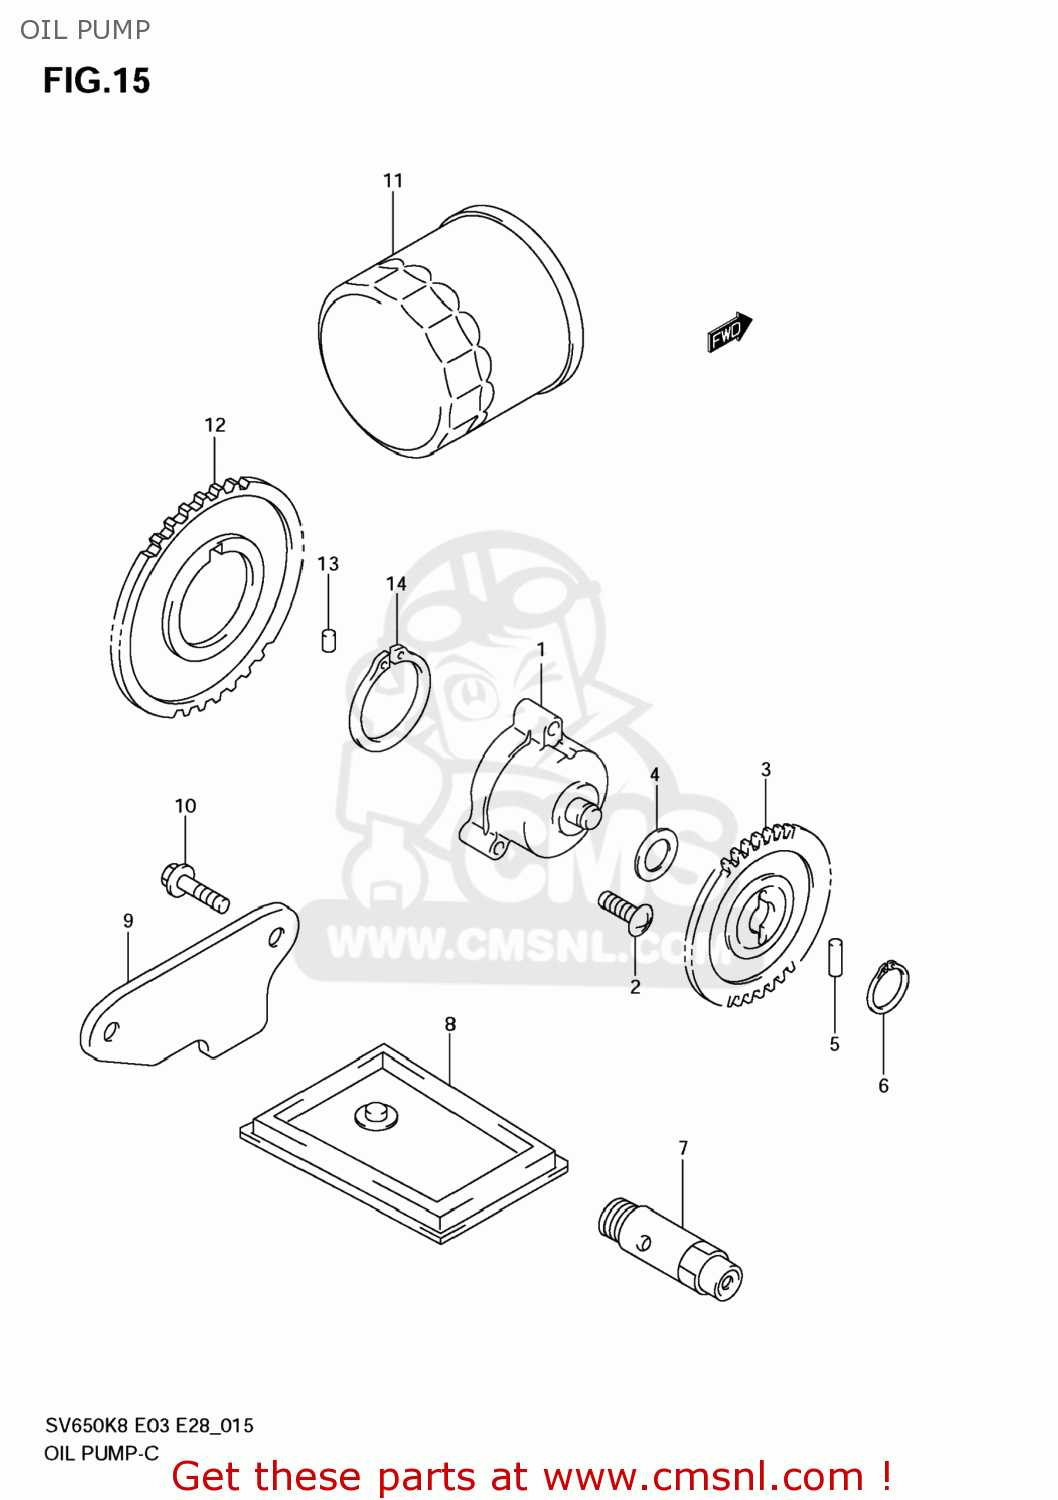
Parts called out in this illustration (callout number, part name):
1	PUMP ASSY,ENGINE OIL
2	BOLT
3	GEAR,ENG OIL PUMP DRIVEN
4	SHIM(10X18X0.5)
5	PIN(4X18.5)
6	CIRCLIP,10MM
7	VALVE ASSY,OIL RELIEF
8	STRAINER,ENGINE OIL
9	CAP,OIL STRAINER
10	BOLT
11	FILTER ASSY,EN
12	GEAR,ENG OIL PUMP DRIVE
13	PIN(6X6)
14	CIRCLIP
